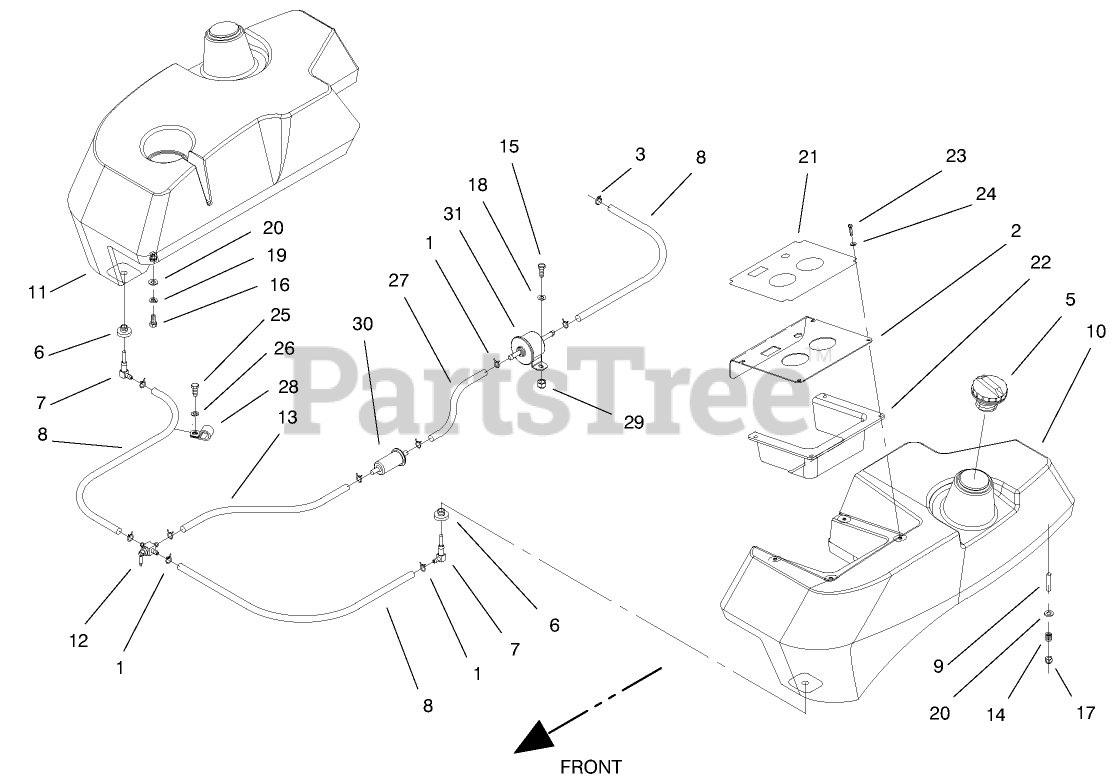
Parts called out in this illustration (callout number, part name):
1	Clamp
2	PANEL-CONTROL
3	Clamp
5	CAP-FUEL
6	Bushing
7	Elbow
8	Fuel Line
9	Stud
10	TANK-FUEL, LH
11	TANK-FUEL, RH
12	Valve-Fuel Line
13	Fuel Line
14	Spring-Fuel Tank
15	SCREW-HH
16	SCREW-HH
17	NUT-LOCK NI
18	WASHER-FLAT
19	WASHER-LOCK
20	WASHER-PLAIN
21	DECAL-CONTROL PANEL
22	SHIELD-PANEL, CONTROL
23	Screw
24	Washer
25	SCREW-HH
26	WASHER-LOCK
27	Fuel Line
28	Clip
29	NUT-HF
30	Filter-Fuel
31	PUMP-FUEL
